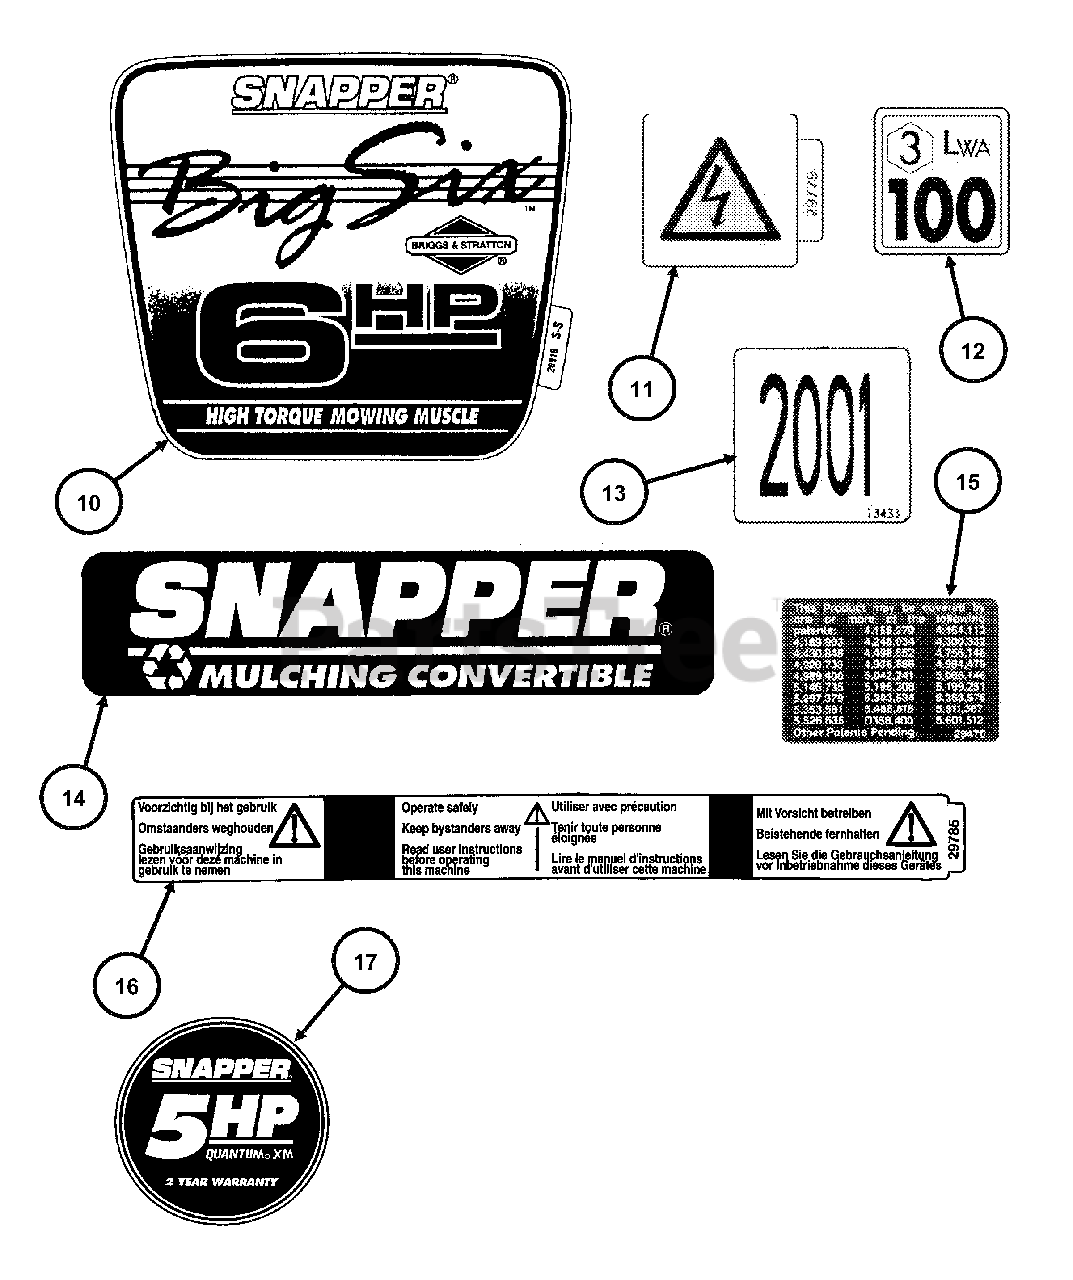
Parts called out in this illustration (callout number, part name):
10	DECAL, 6.0 HP Briggs XTL
11	DECAL, Spark Plug (European)
12	DECAL, Noise Control (European)
13	DECAL, 2001 Year of Manufacture
14	DECAL, Mulching Convertible
15	DECAL, Patent Numbers
16	DECAL, Handle International Warning
17	DECAL, Snapper (3.87" Diameter)
